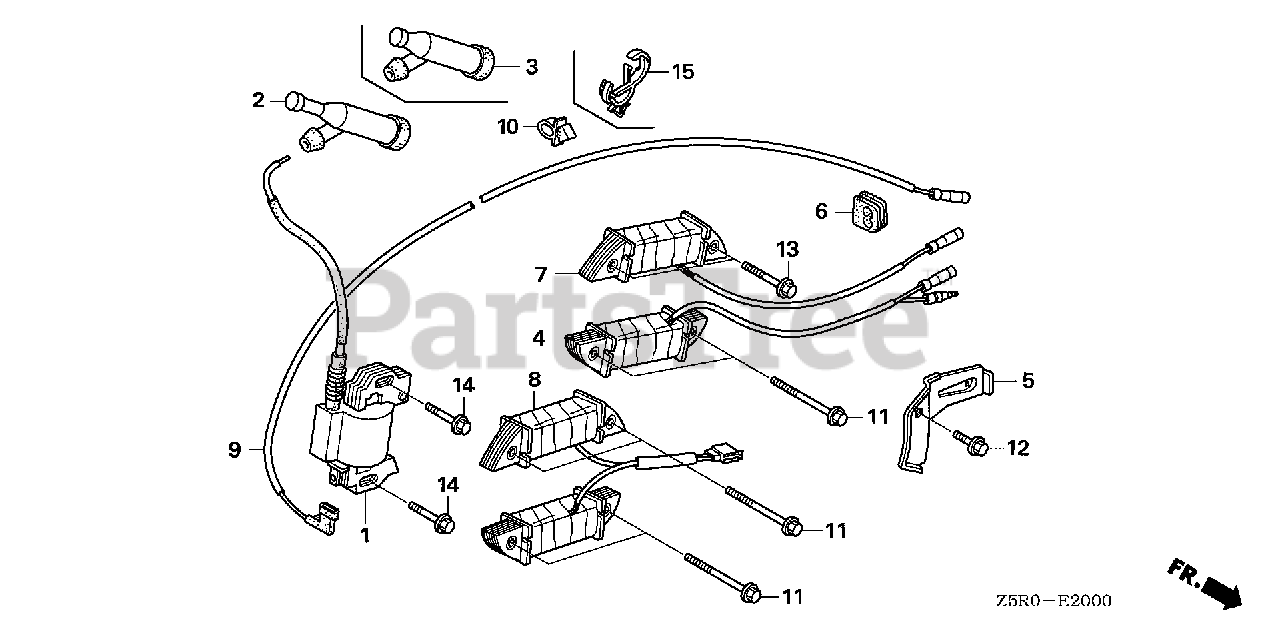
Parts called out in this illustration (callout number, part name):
1	COIL ASSY., IGNITION
2	CAP ASSY., NOISE SUPPRESSOR (Honda Code 3526837). (NICHIWA Y-EZ RTFM256)
5	CLAMP, WIRE
6	GROMMET, WIRE
7	COIL ASSY., CHARGE (1A)
9	WIRE, STOP SWITCH (430MM)
10	HOLDER, STOP SWITCH WIRE Use up to Engine SN 2056819.
12	BOLT, FLANGE (6X12) (CT200)
13	BOLT, FLANGE (6X35)
14	BOLT, FLANGE (6X28) (CT200) Use up to Engine SN 1530314.
